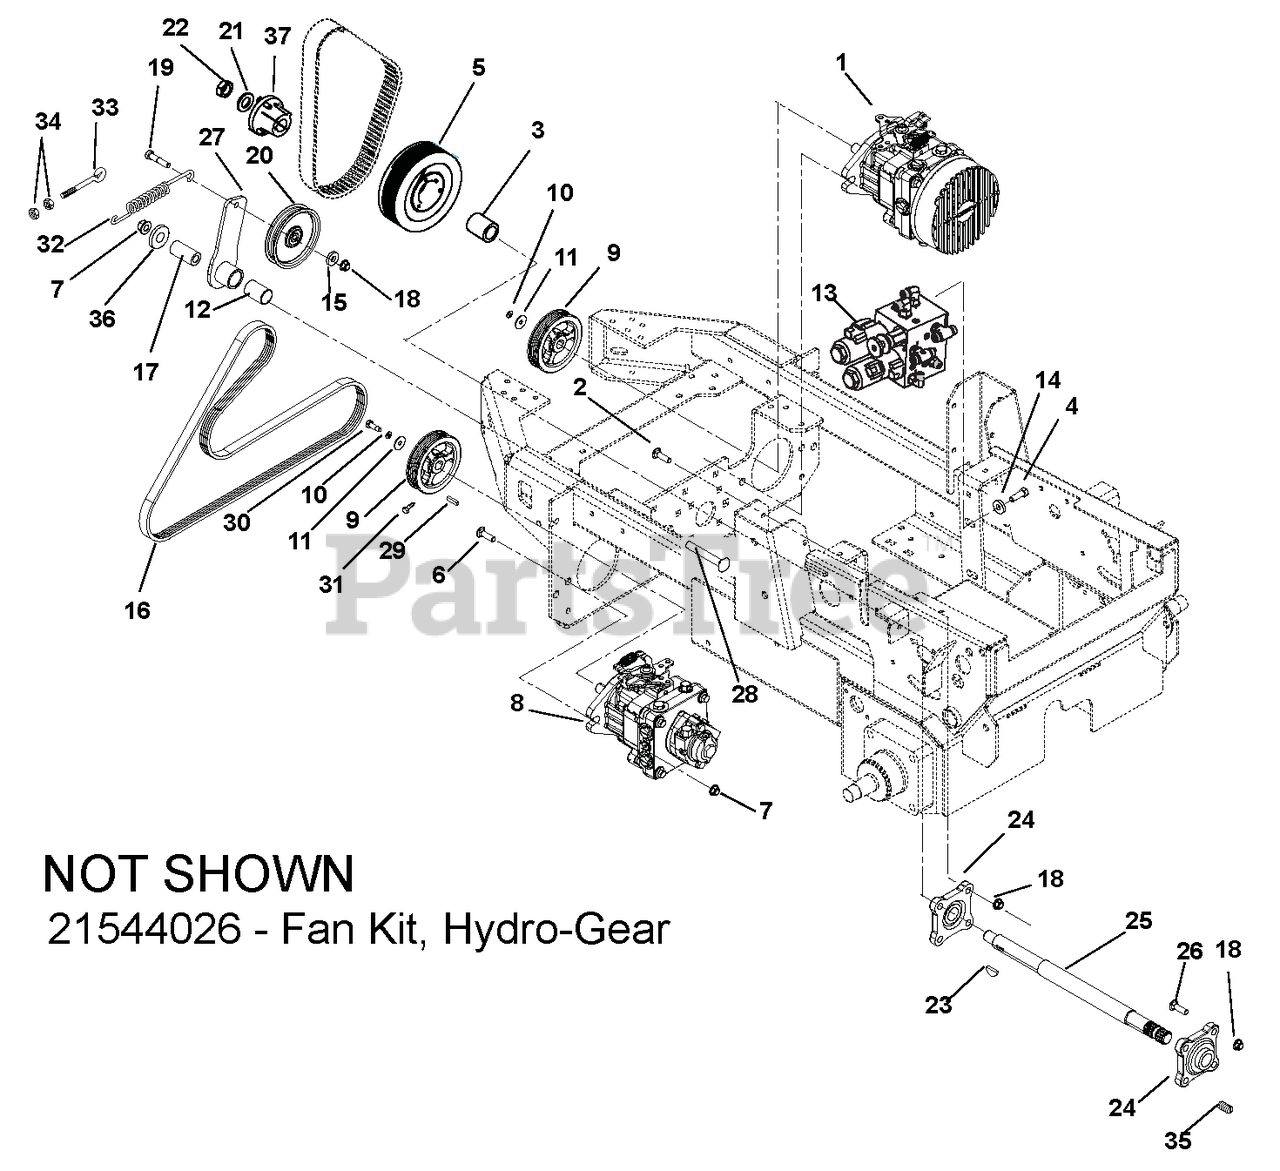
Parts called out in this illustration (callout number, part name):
1	PUMP, HYD. BDP-21L -LH RAPIDXZ
2	BLT-RDHDSQNK .38-16X1.25 G5YZ
3	SPCR, 1.0ID X 1.5OD X 1.81 LNG
4	@BLT-HEX .31-18X1.00 GR5 YWZC
5	PULLEY,8G POLY V,L-SECT,6.4"OD
6	BLT-RDHDSQNK .50-13X1.50 G5YZ
7	@NUT-LK-NYL-FLG .50-13 YWZC
8	PUMP,HYD.BDP21L RH/AUX RAPIDXZ
9	SHEAVE - POLY-V .671 X 4.125
10	@WSHR-LK .25X.062 REG YWZC
11	WSHR-FL-STL .281X1.000X.063
12	BSHG, 1.00 X 1.125 X 1.937
13	VALVE,2 SPOOL MAINIFOLD BLOCK
14	WSHR-FL-STL .344X1.125X.135
15	@WSHR-FL-STL.406X.812X.065 YWZ
16	POLY V-BELT, K-5 RIBS
17	BSHG, SPCR .502X.997X2.03 PM
18	@NUT-LK-NYL-FLG .38-16 YWZC
19	@BLT-HEX .38-16X2.25 GR5 YWZC
20	IDLER-FLAT 4.00 X .38 NWHAMSHR
21	@WSHR-FL-STL.812X1.50X.135YWZC
22	NUT-JAM CTRLK .75-16 YWZC
23	KEY-WDRF .25X.750X.313 SAE91
24	BEARING, 1"ID 4BOLT-TRASH SEAL
25	SHAFT, PTO JACK SHAFT RAPIDXZ
26	@BLT-HEX .38-16X1.25 GR5 YWZC
27	ASM, IDLER PIVOT ARM
28	@BLT-RDHDSQNK .50-13X3.50 G5YZ
29	KEY, SQ 5 X 5 X 30MM PLAIN
30	@BLT-HEX M6-1X16 YWZC
31	SCR-SKH .25-20 X .50 PH & OIL
32	SG-TENS .135X.69X5.75 WLD 150
33	BLT-EYE .375-16X2.50 YWZC
34	@NUT-HEX .38-16 YWZC
35	SCREW, SET .25-28X.38
36	WSHR-FL-STL.511X1.441X.125 YWZ
37	BUSHING,TAPER, 1" SHAFT
